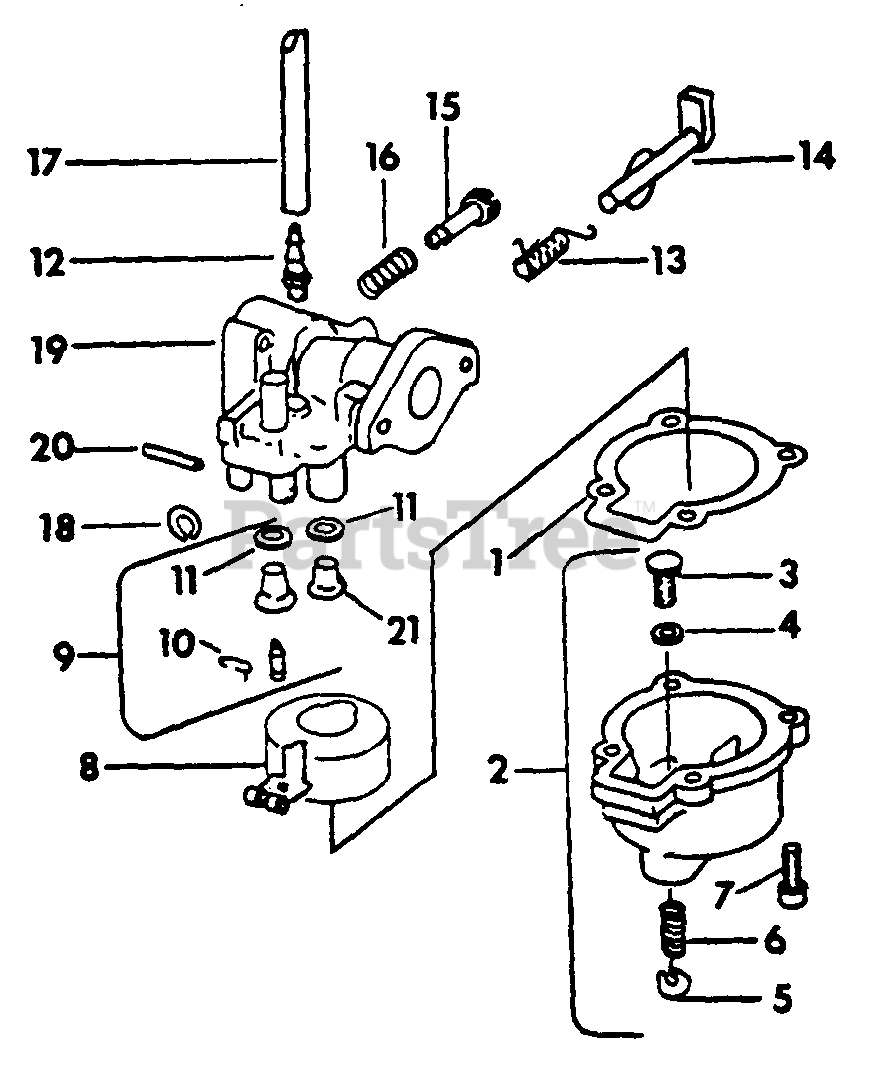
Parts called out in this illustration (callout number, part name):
1	GASKET, FLOAT CHAMBER
2	FLOAT CHAMBER & DUMP VALVE ASSY
3	STEM, VALVE
4	SEAT, VALVE
5	KEEPER, VALVE
6	SPRING, VALVE
7	SCREW, 8-32 X 1/2 ZND FIL-HD SLT MACH
9	FLOAT VALVE & SEAT
11	WASHER, FLOAT VALVE SEAT
12	CONNECTOR, TUBING
13	SPRING, THROTTLE
14	SHAFT W/DISC, THROTTLE
15	SCREW, AIR ADJ
16	SPRING, NEEDLE ADJ
17	TUBING, PRIMER
19	BODY ASSY, CARBURETOR
20	PIN, FLOAT ARM HINGE
21	PLUG, NOZZLE
